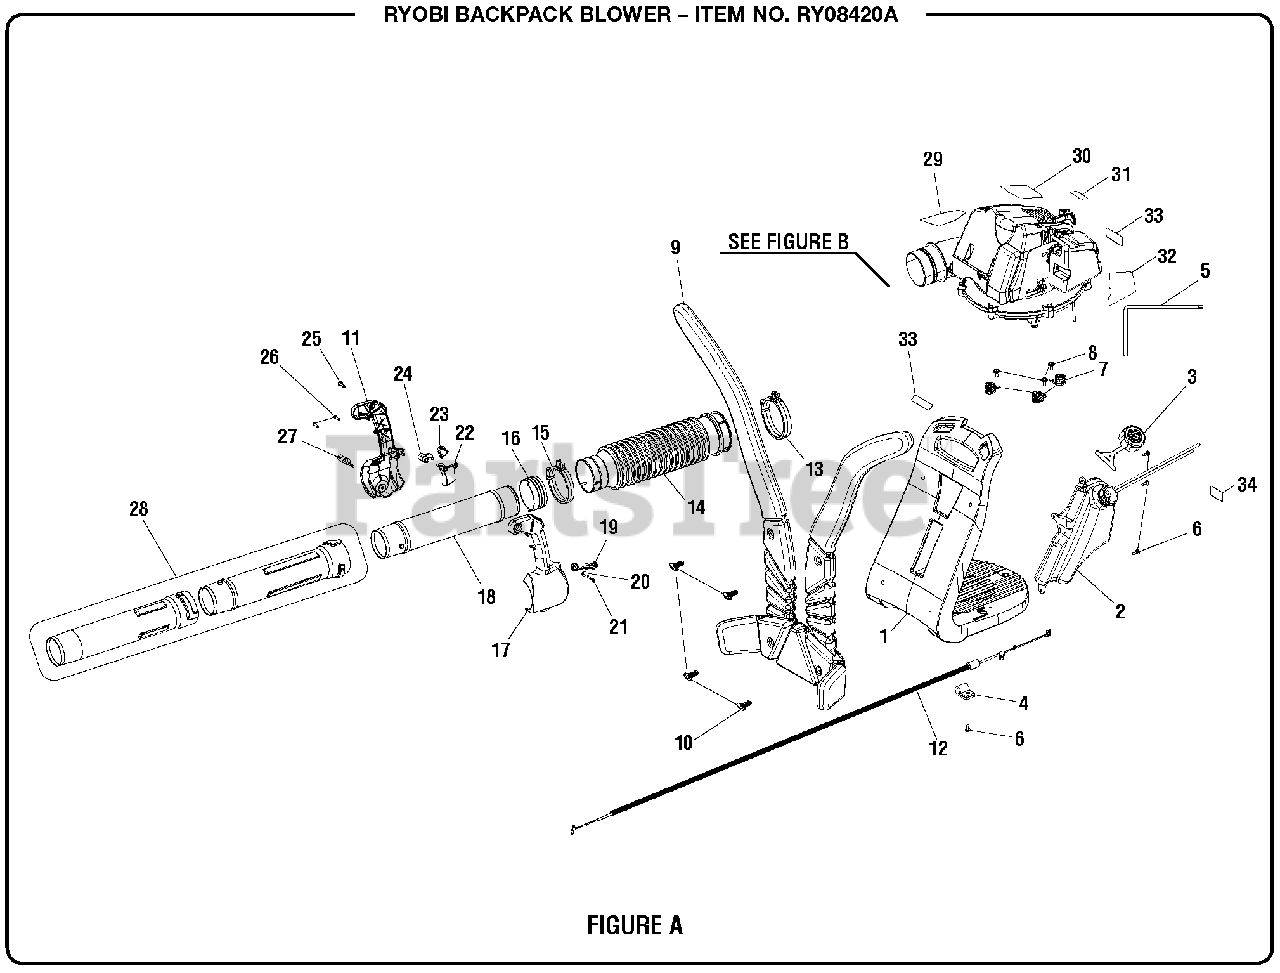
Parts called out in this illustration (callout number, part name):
2	Fuel Tank Assembly
3	Fuel Cap Assembly
4	Cable Clamp
5	Wrench (T-25)
6	Screw (10-14 x 14 mm)
8	Screw (10-14 x 16 mm)
10	Harness Snap Fastener
11	Right Hand Handle
12	Throttle Cable
13	Clamp Assembly (Large)
15	Clamp Assembly (Small)
16	Upper Blower Tube Bushing
17	Left Hand Handle
18	Upper Tube
19	Cruise Lever
20	Washer (OD12 x ID4.3 x 1.5t)
21	Screw (8-14 x 25 mm)
23	Stop Switch
24	Trigger Lock
25	Screw (10-14 x 3/4 in.)
26	Screw (M4 x 16 mm, Pan Hd.)
28	Blower Tube Assembly
29	Combustion Warning Label
30	Model Label
31	Choke Label
32	Start Instructions Label
33	Logo Label
34	Warning Label
